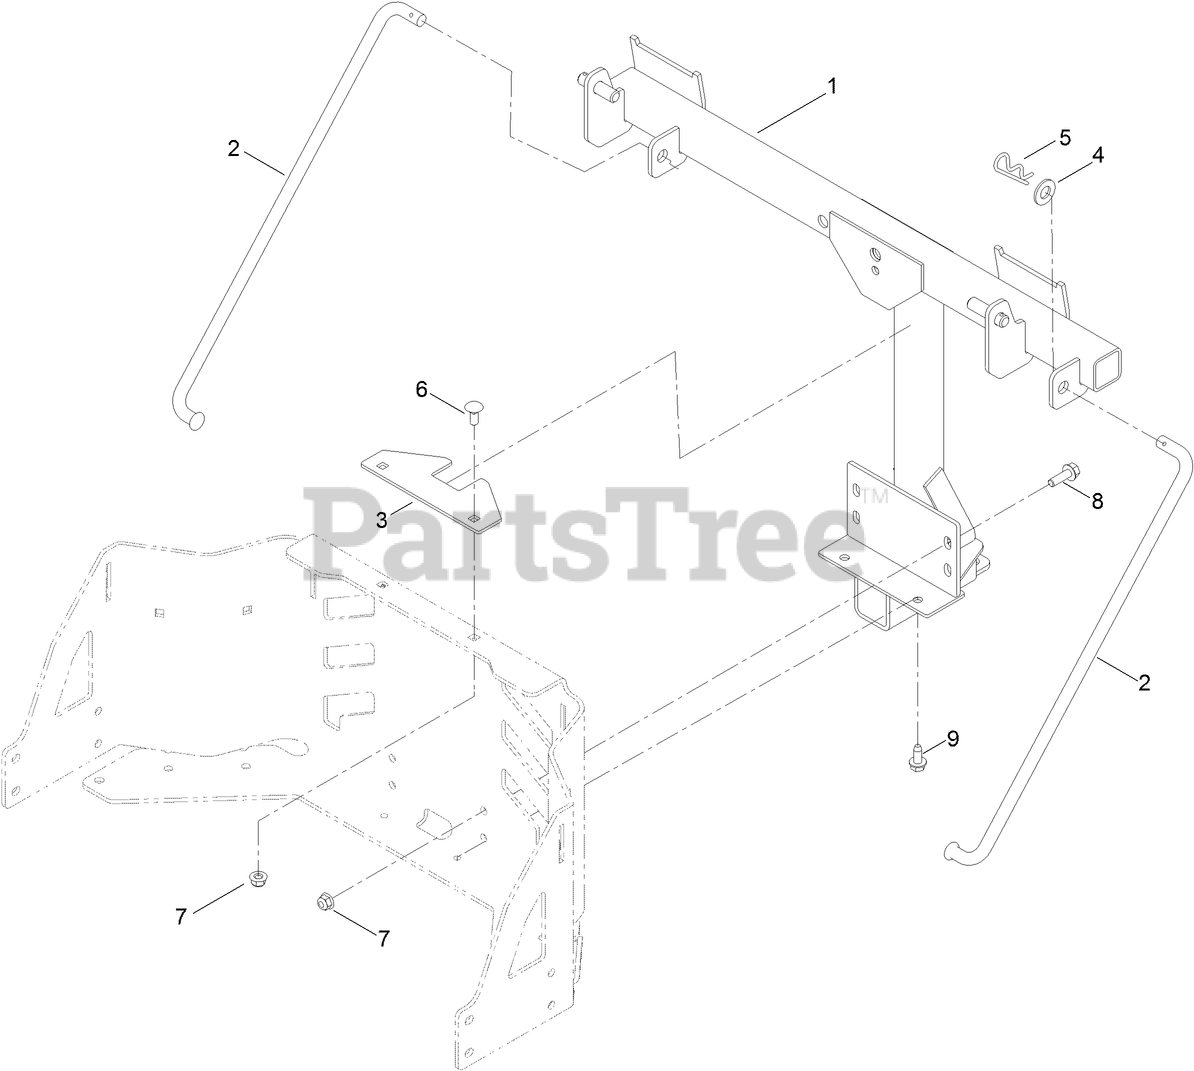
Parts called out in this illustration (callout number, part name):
1	FRAME-PIVOT
2	ROD-SUPPORT
3	BRACKET-STABILIZER
4	WASHER-FLAT
5	PIN-HAIR
6	BOLT-CARR
7	NUT-HF, NI
8	SCREW-HHF
9	SCREW-HWHTF
